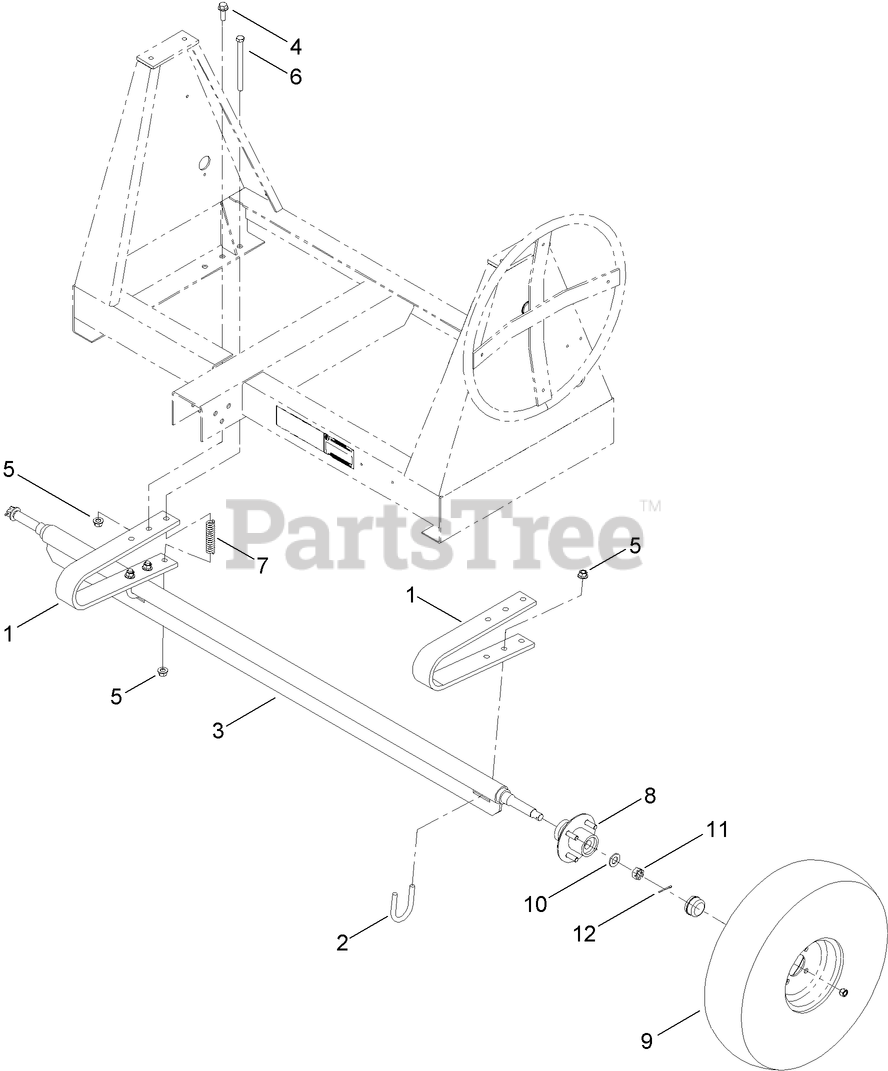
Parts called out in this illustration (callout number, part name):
1	SPRING-LEAF
2	BOLT-U
3	AXLE-SPRING
4	SCREW-HHF
5	NUT-LOCK
6	SCREW-HH
7	SPRING-COIL
8	HUB ASM
9	TIRE AND RIM ASM
10	WASHER-FLAT
12	PIN-COTTER
